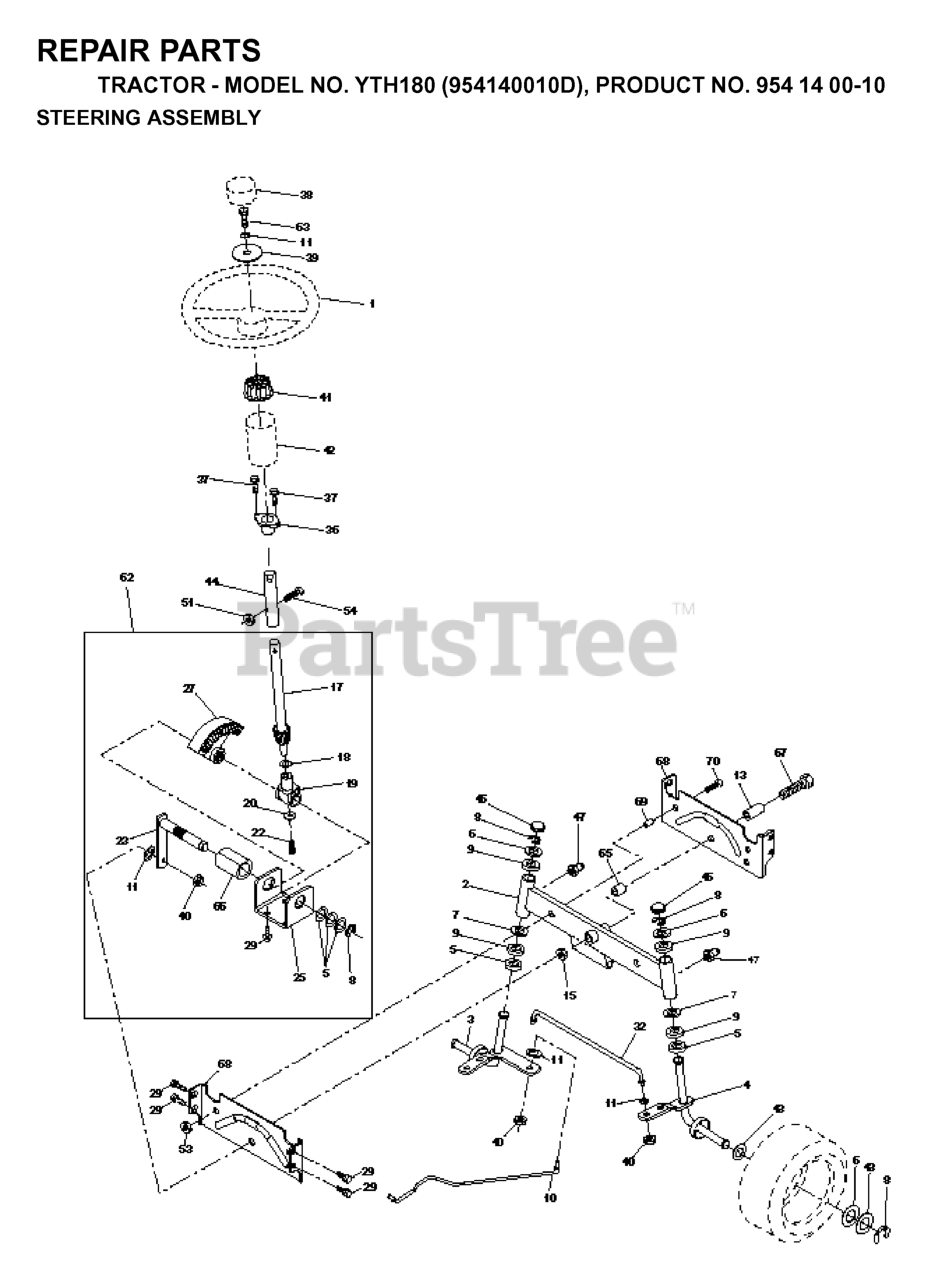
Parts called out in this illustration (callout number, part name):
1	STEERING WHEEL
2	FRONT AXLE ASSY
3	SPINDLE ASM LH
4	SPINDLE ASM RH
5	THRUST WASHER
9	BRNG T
10	LINK.DRAG.DROPPED.LT
11	WASHER, LOCK 3/8
13	BEARING AXLE
15	NUT-LOC,FLANGE LT
17	SHAFT ASM STEERING
18	THRUST WASHER
19	SHAFT,SUPPORT
20	WASHER
22	SCREW HEX SOCKET 1/4-20 X 5/8
23	SHAFT PITMAN
25	BRACKET STEERING
26	BUSHING LINK DRAG BLK LR
27	GEAR.SECTOR
28	WASHER
29	SCREW
30	COTTER PIN
32	ROD ASSY/TIE BALL
36	BUSHING, STEERING
37	SCREW.TT.#10-32X.5.3/8.FLANGE
38	INSERT,STR WHEEL
39	WASHER T
40	GRIPCO NUT
41	ADAPTER LT
42	BOOT, STEERING
44	EXT SHAFT STEERING
46	CAP.SPINDLE.BLACK
47	ZERK M
51	NUT.71038.31-18.HEX.NYLOCK
54	BOLT.5/16-18X1-1/4 FULL.THREAD
62	KIT, STEERING ASSEMBLY
65	SPACER AXLE
66	BEARING ARM
67	Bolt, Hex 5/8 -11 x 2 - 3/4 Gr. 5
68	AXLE, BRACE
69	SPACER BRACE AXLE
70	BOLT.HEX
